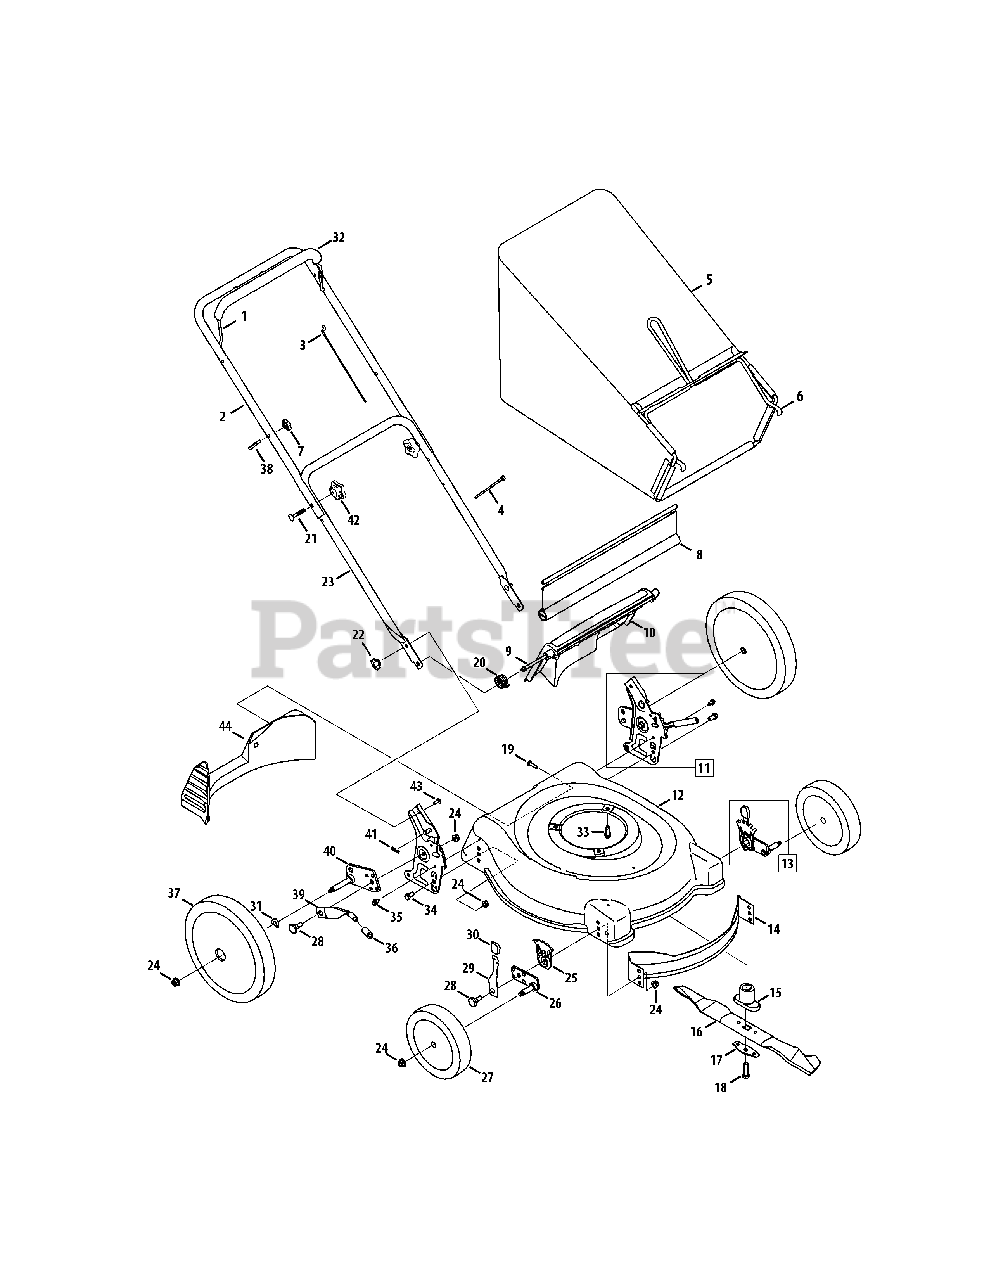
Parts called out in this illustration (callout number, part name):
1	Blade Control
2	Upper Handle
3	Control Cable, 40"
4	Cable Tie
5	Grass Bag
6	Grass Bag Frame
7	Handle Knob
8	Trail Shield
9	Pivot Rod
10	Rear Discharge Door
11	Handle Bracket Assy. - LH
11	Handle Bracket Assy. - RH
12	Deck 21-inch
13	Front Hgt. Adj. Assy., LH
13	Front Hgt. Adj. Assy., RH
14	Front Baffle
15	Blade Adapter, #6 x 2.15
16	21-inch Mulching Blade
17	Bell Blade Support
18	Hex Screw, 3/8-24 x 2.5
19	Screw HL, 1/4-15 x 1.00
20	Torsion Spring - RH
21	Carriage Bolt, 5/16-18 x 2
22	Wing Nut
23	Lower Handle
24	Flange Lock Nut 3/8-16
25	Height Adjustment Plate
26	Pivot Arm Assy RH
26	Pivot Arm Assy LH
27	Front Wheel, 8 x 2.125
28	Shoulder Scr., .5D x .385
29	Front Spring Lever
30	Height Adjust Knob
31	Spring Washer
32	Deluxe Bail Cover
33	TT Screw, 3/8-16 x 1.0
34	Hex Screw, 3/8-16 x .75
35	TT Screw, 1/4-20 x .625
36	Foam Grip
37	Rear Wheel, 12 x 2.125
38	Eye Bolt
39	Spring Lever
40	Pivot Arm Assy - RH
40	Pivot Arm Assy - LH
41	Hairpin Clip
42	Star Knob
43	Carriage Bolt ,1/4-20 x .75
44	Rear Baffle
